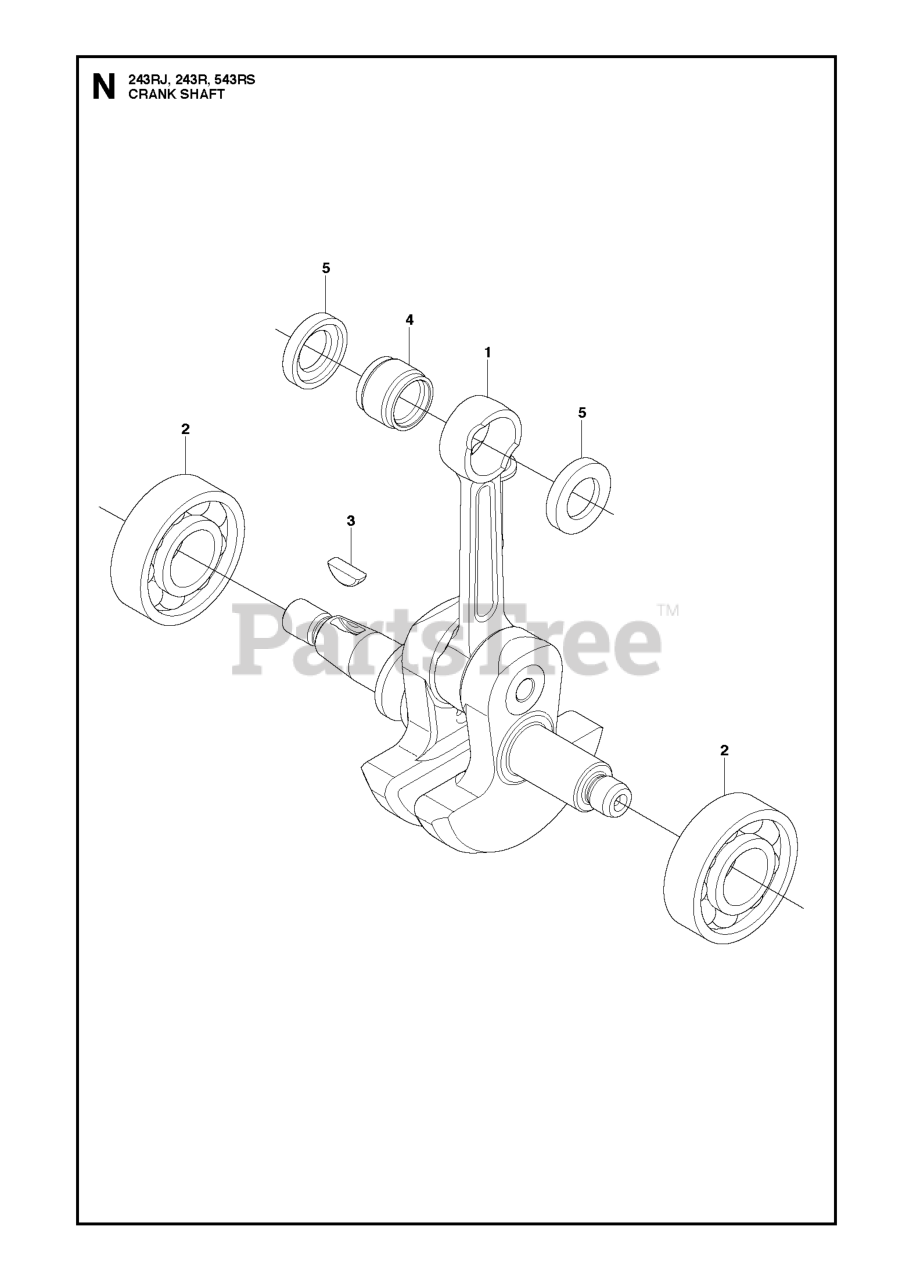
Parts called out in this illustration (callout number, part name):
1	CRANK SHAFT ASSY
2	BEARING
4	BEARING
5	THRUST WASHER
